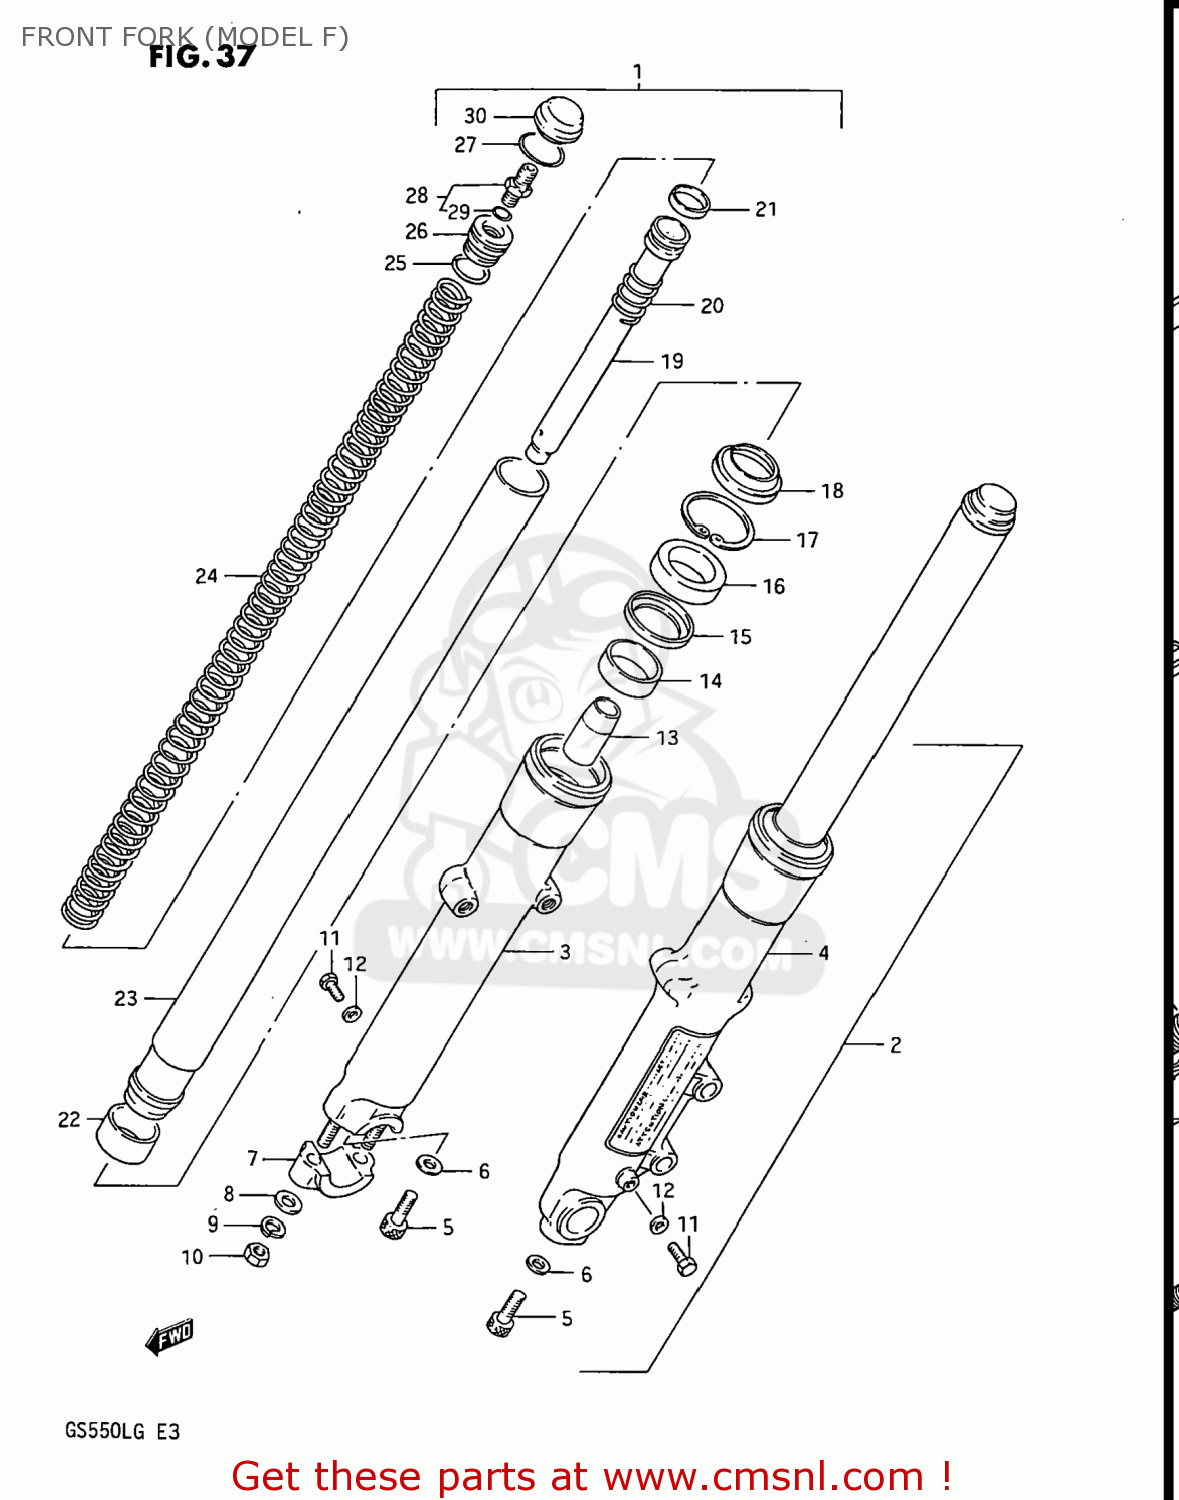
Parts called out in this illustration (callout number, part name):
1	DAMPER ASSEMBLY,RIGHT
2	DAMPER ASSEMBLY,LEFT
3	TUBE,FORK,OUTER,RIGHT
4	TUBE,FORK,LEFT,OUTER
5	BOLT(8X27)
6	GASKET (NAS)
7	HOLDER,AXLE,RIGHT
8	WASHER
9	LOCK WASHER
10	NUT (8MM)
11	BOLT
12	GASKET,DRAIN,PLUG (NAS)
13	PIECE,OIL LOCK
14	BUSHING,GUIDE
15	SPACER,SEAL
16	OIL SEAL,FRONT FORK
17	CIRCLIP,INNTERNAL
18	SEAL,DUST
19	CYLINDER,FRONT FORK
20	SPRING
21	RING,PISTON
22	PISTON
23	TUBE,FORK,INNER
24	SPRING,FRONT FORK
25	O RING
26	GUIDE,SPRING
27	RING,STOPPER
28	VALVE,AIR
29	O-RING (D:3.8 ID:19)
30	CAP,FR FORK
